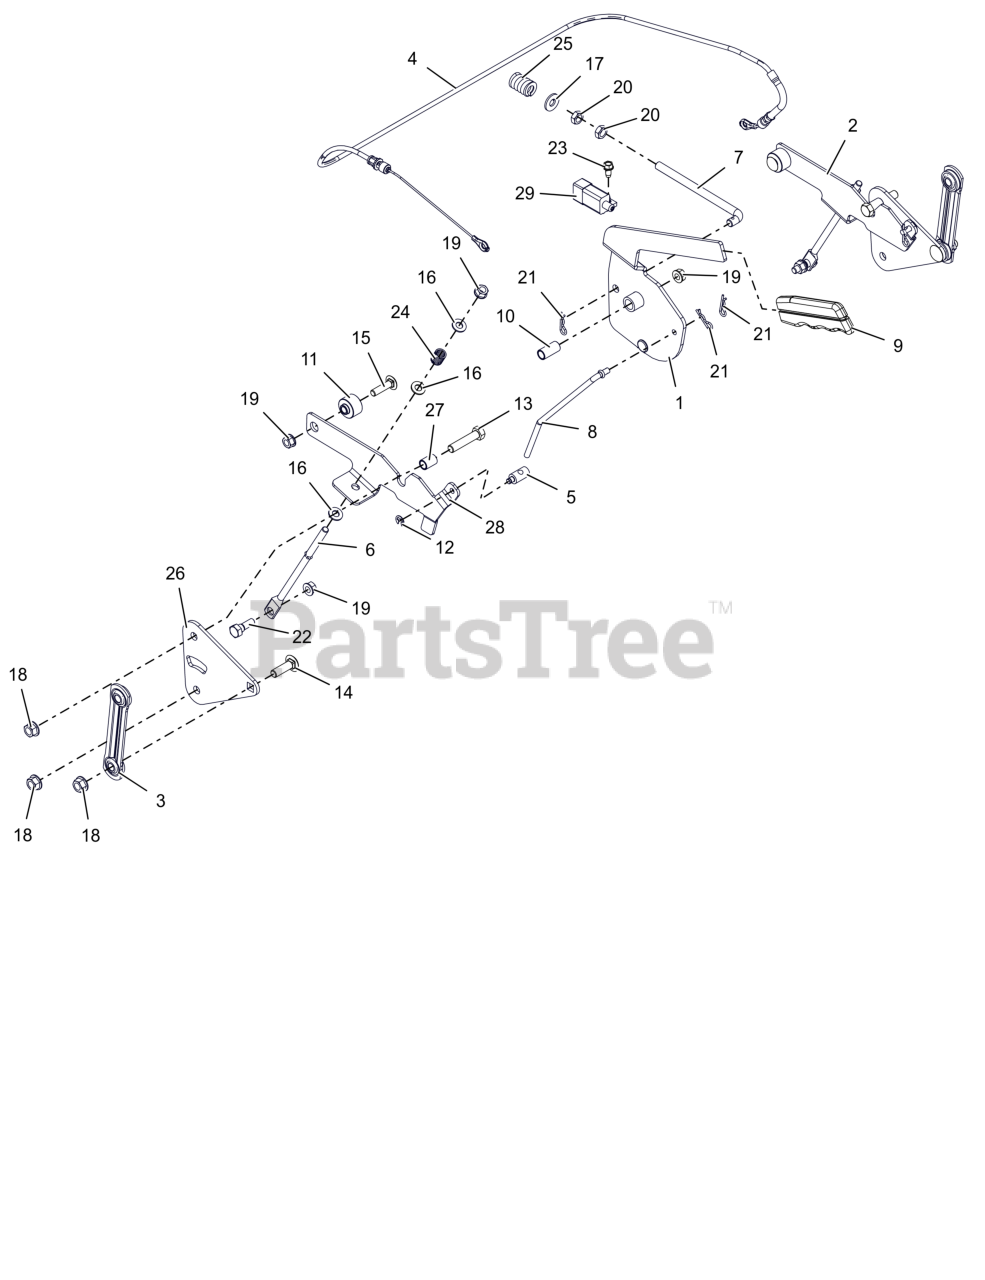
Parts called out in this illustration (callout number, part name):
1	LEVER, PARKING BRAKE
2	ARM, BRAKE - LH (W/PIN)
3	LINK, STAMPED STEERING
4	CABLE, BRAKE - PARKING
5	TRUNION, 1/4-20
6	ROD, LINK - TRANSMISSION BRAKE
7	ROD, OVER CENTER
8	ROD, BRAKE LINK
9	GRIP, PARKING BRAKE (GREY)
10	BSHG-SLV .385X.500X1.045
11	SPCR, FLANGE
12	RG-RTNG-EXT .250X.025
13	BLT, HEX .38-16X1.75 G5 ZCC
14	BLT,RHSSN .38-16X1.25 G5 ZCC
15	BLT, RHSSN.31-18X1.25 G5 ZCC
16	WSHR,FLT .344X.688X.065 ZCC
17	WSHR,FLT .375X.875X.083 ZCC
18	NUT-LK-TOP-FLG .38-16 ZC120
19	NUT-LK-TOP-FLG .312-18 GF ZCC
20	NUT-JAM .375-16 G2 ZCC
21	PIN, HAIR #213 .08X1.19 ZCC
22	BOLT,SHLDR .38X.25 -.31-18X.75
23	SCR-TAP .25-20X.50 HWH ZCC
24	SPRING, COMPRESSION
25	SG-COMP .187X.56X1.62
26	PLATE, TRANSAXLE (BLACK)
27	SPCR SLEEVED .385X.500X.718
28	ARM, BRAKE - RH
29	SWITCH-BRAKE NO/NO-POST & HOLE
